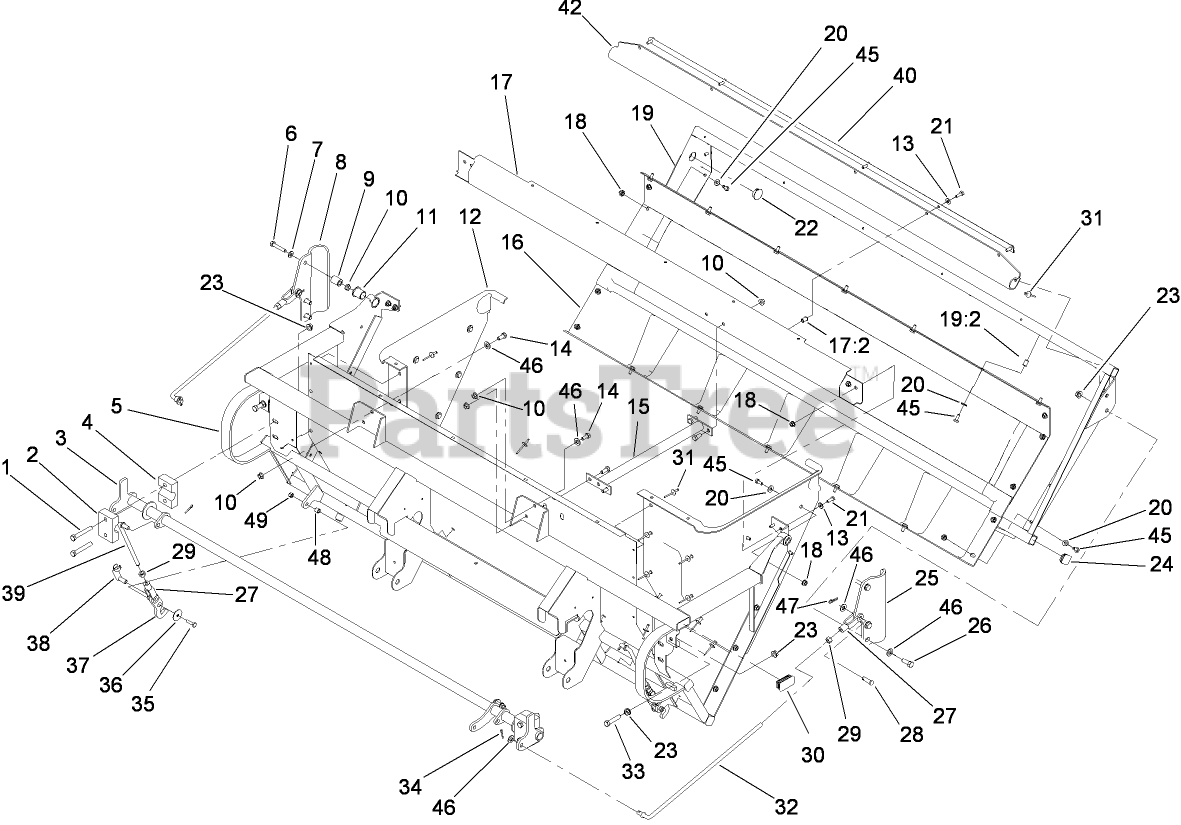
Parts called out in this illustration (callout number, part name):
1	SCREW-HH
2	BLOCK-BEARING
3	LINK-INTERMEDIATE
4	HALF-BLOCK, BEARING
5	UPRIGHT-BAGGER
6	SCREW-HH
7	WASHER-PLAIN
8	ARM-HINGE, RH
9	PIN-PIVOT, HINGE
10	NUT-HF
11	Bushing
12	PANEL-BAGGER, RH
13	WASHER-FLAT
14	SCREW-HH
16	BAG AND BOTTOM PANEL ASM
17	REAR CROSSMEMBER ASM
17:2	INSERT-NUT
18	NUT-HF
19	DOOR ASM
19:2	INSERT-NUT
20	WASHER-FLAT
21	SCREW-HH
22	PLUG-DOME
23	NUT-HHF, WHIZ
25	ARM-HINGE, LH
26	SCREW-HH
27	YOKE-LINKAGE, BRAKE
28	PIN-CLEVIS
29	NUT-HEX
31	RIVET-BLIND
32	LINK-HINGE
33	SCREW-HH
34	PIN-COTTER
35	SCREW-HH
36	WASHER-FLAT
38	Pin-Spring, Clevis
39	LINK-HANDLE
40	STRAP-HOLD DOWN
42	SEAL-DOOR HINGE
45	SCREW-HH
46	WASHER-FLAT
47	PIN-COTTER
48	SPACER
49	NUT-LOCK, NI
